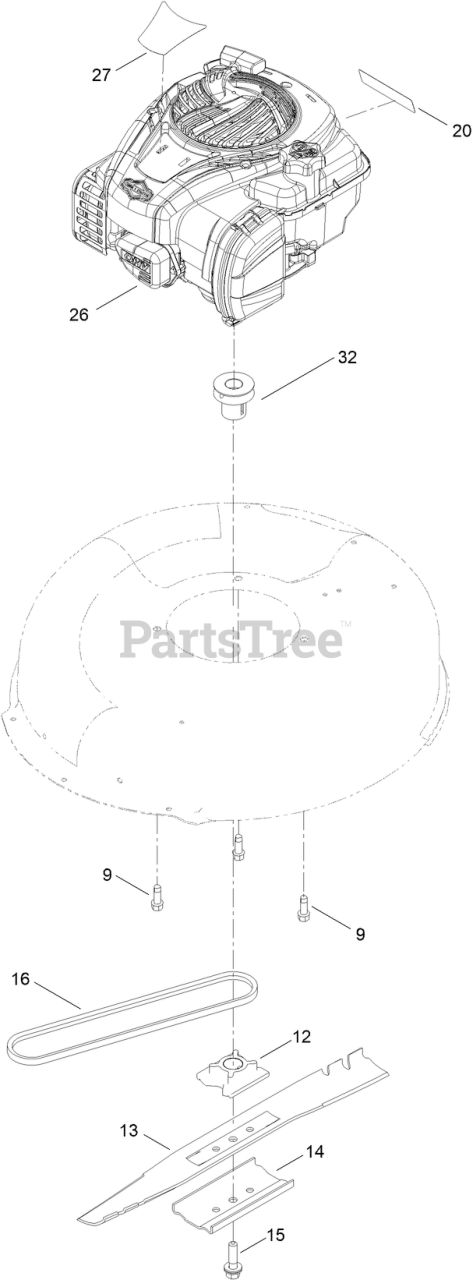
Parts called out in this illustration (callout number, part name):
9	SCREW-TAPTITE
12	RETAINER-BLADE
14	SUPPORT-BLADE
15	BOLT-BLADE
20	DECAL-ARRESTOR, SPARK
27	DECAL-ENGINE
